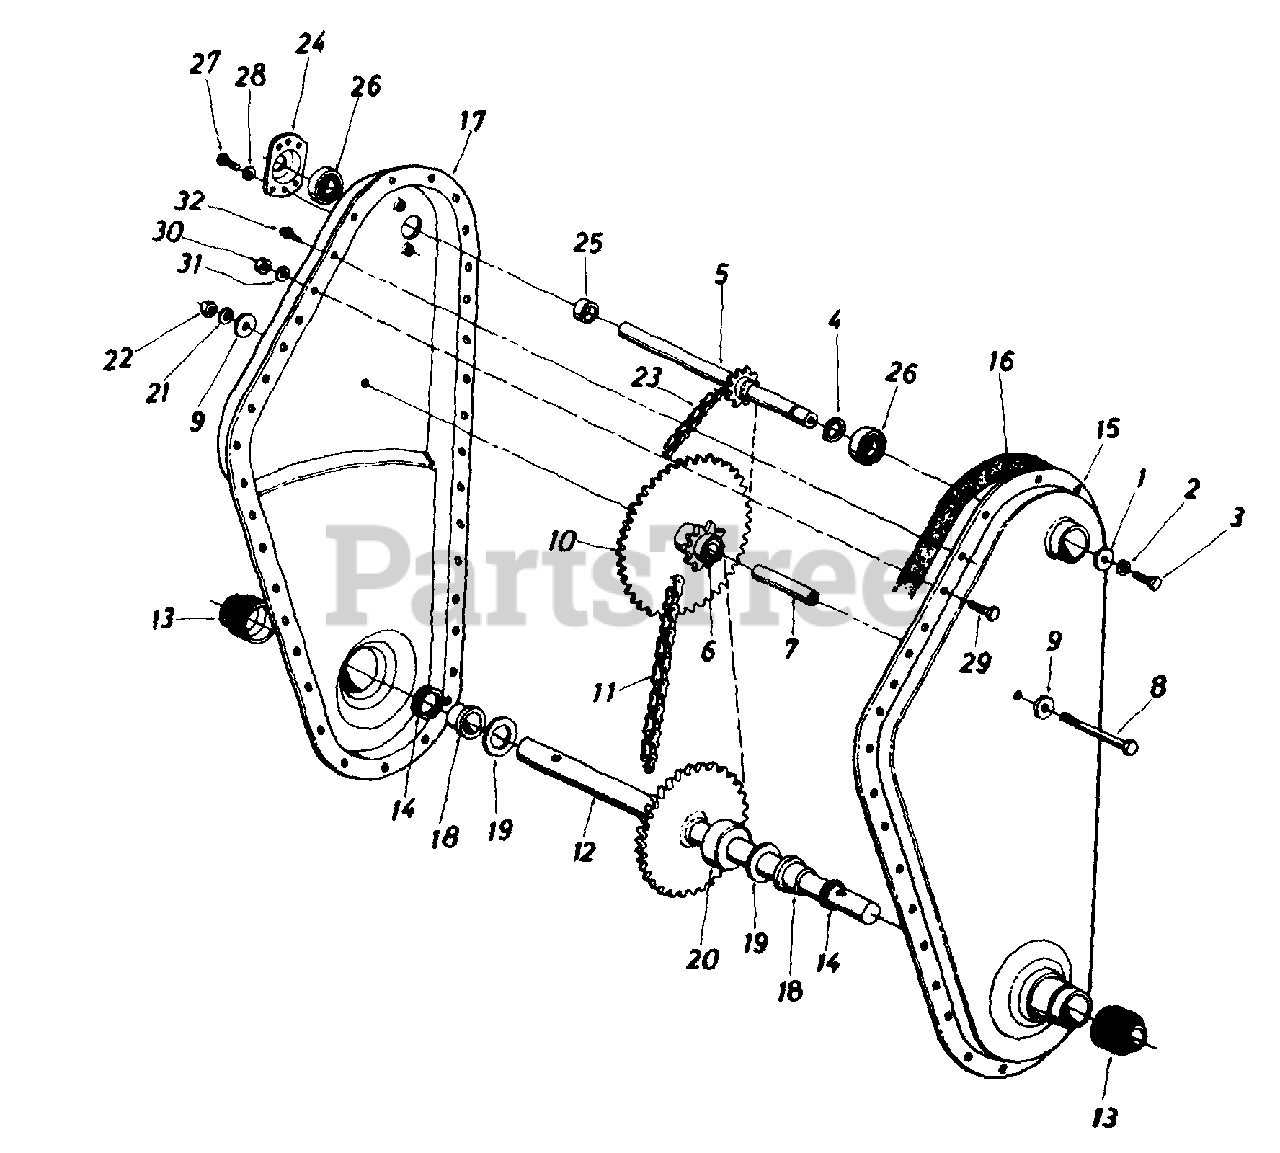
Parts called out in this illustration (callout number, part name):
2	L-Wash. 1/4" I.D.
3	Hex Bolt 1/4-28 x .62" Lg. w/Patch
4	External Snap Ring - 5/8" Dia.
5	Input Shaft Ass'y.
6	Bearing 5/8" I.D. x 3/4" O.D. x 1.860" Lg.
7	Sprocket Hub Tubing 3/8" I.D. x 5/8" O.D. x 1.90
8	Hex Bolt 3/8-24 x 2.75" Lg.
9	Fl-Wash. 3/8" I.D. x 1.25" O.D. x .10
10	Sprocket Ass'y.
11	#50 Chain 5/8" Pitch x 46 Links Endless
12	Tine Shaft Ass'y.
13	Dust Cup
14	Seal Ring Single Lip, Springless
19	Fl-Thrust Wash. 1.0" I.D. x .03 Thk.
20	Step Spacer
21	L-Wash. 3/8" I.D.
22	Hex Nut 3/8-24 Thd.
23	#35 Chain 3/8" Pitch x 52 Links Endless
24	Bearing Housing 1.38" I.D.
26	Ball Bearing .625" I.D. x 1.38" O.D. x .437
27	Hex Wash. SF-Tap Scr. 1/4-20 x .50" Lg.
28	L-Wash. 1/4" I.D.
29	Hex Bolt 5/16-18 x .75" Lg.
30	Hex Nut 5/16-18 Thd.
31	L-Wash. 5/16" I.D.
32	Hex Wash. SF-Tap Scr. 1/4-20 x .50" Lg.
